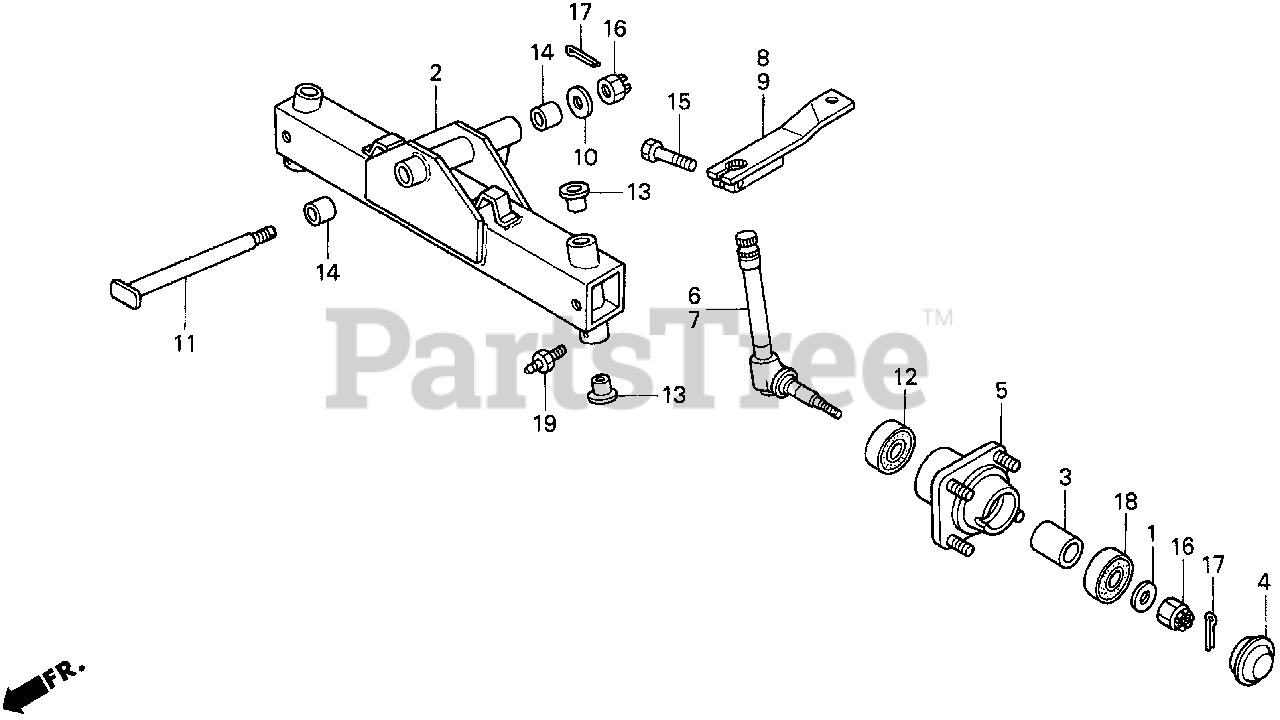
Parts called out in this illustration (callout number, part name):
1	WASHER (14MM)
3	COLLAR, FR. AXLE
4	CAP, FR. HUB
5	HUB, FR. AXLE
6	KNUCKLE, R. FR.
7	KNUCKLE, L. FR.
8	ARM, R. FR. KNUCKLE
9	ARM, L. FR. KNUCKLE
10	WASHER, THRUST (14X30X2.5)
11	PIN, CENTER
12	BEARING, RADIAL BALL (62/22)
13	BUSH (28X25X20)
14	BUSH (20X18X20)
15	BOLT, HEX. (12X40)
16	NUT, CASTLE (14MM)
17	PIN, COTTER (3.0X45)
18	BEARING, RADIAL BALL (6205UU)
19	FITTING, GREASE (A.76)
